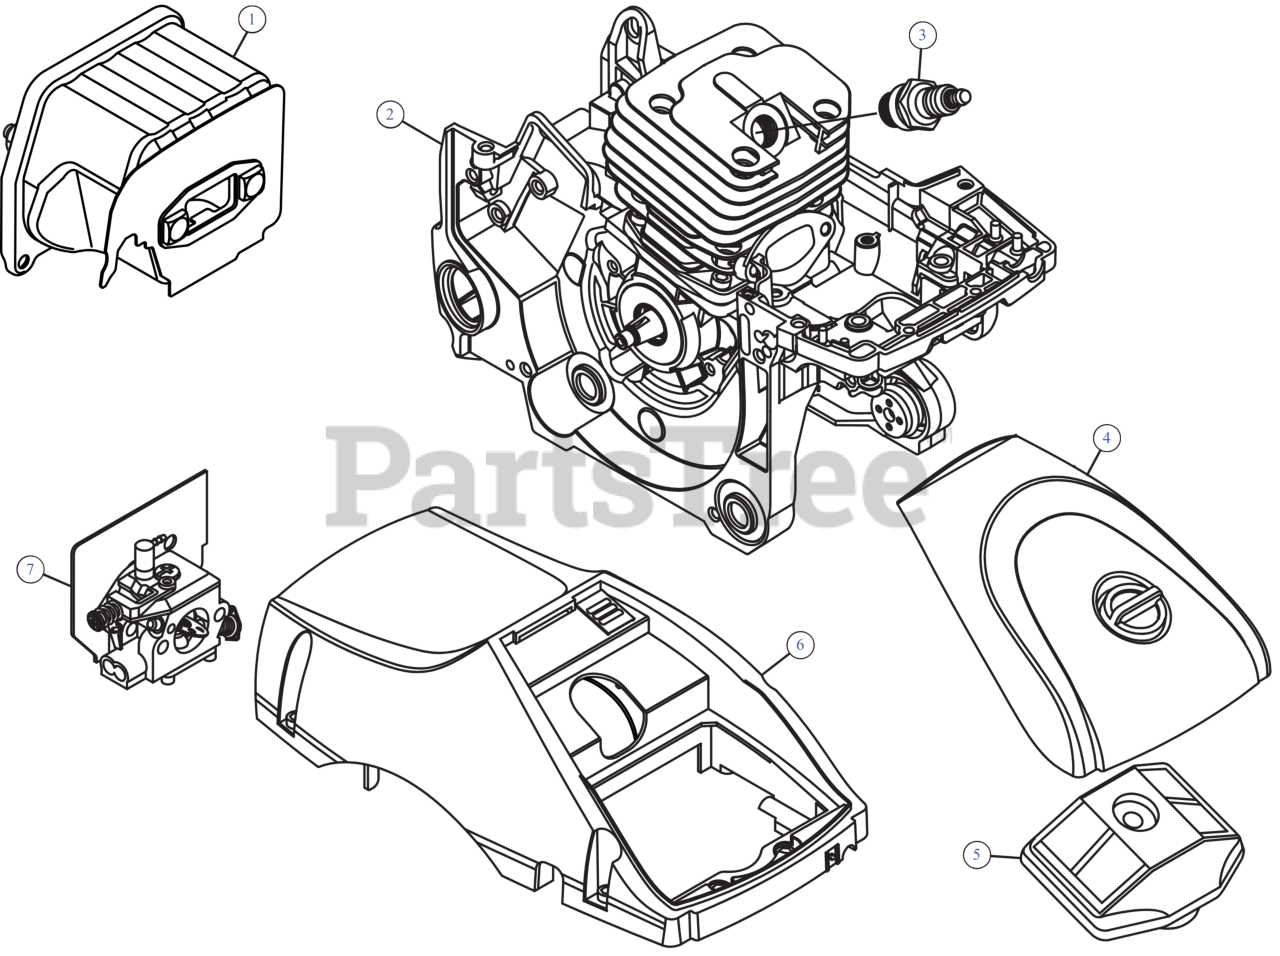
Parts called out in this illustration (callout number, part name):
1	MUFFLER ASSEMBLY
2	SHORTBLOCK 46CC
3	SPARK PLUG:L8RTF YD4500-26200
4	AIR FILTER COVER ASSEMBLY
5	AIR FILTER W/SEAL
6	COVER
7	CARBURATOR
